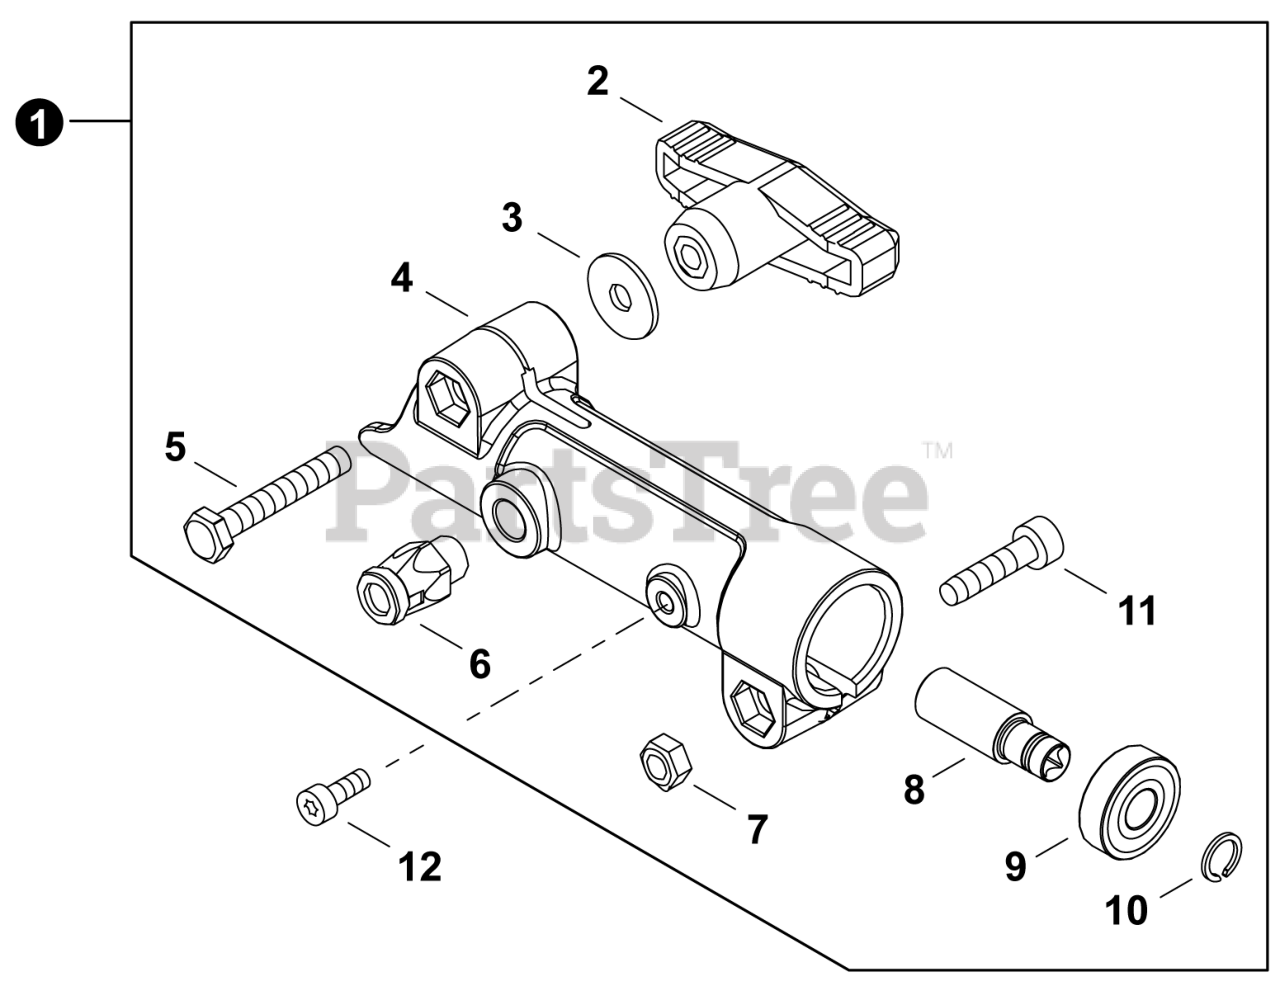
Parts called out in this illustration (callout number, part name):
1	COUPLER ASSY
2	THUMBSCREW
3	WASHER 6.6x20x1.6
4	COUPLER
5	BOLT 6x40
6	LATCH ASSY
8	CONNECTOR, DRIVESHAFT
9	BEARING, BALL 609ZZ
10	RING, SNAP 9
11	BOLT, TORX 6x25
12	BOLT, TORX 5x10
